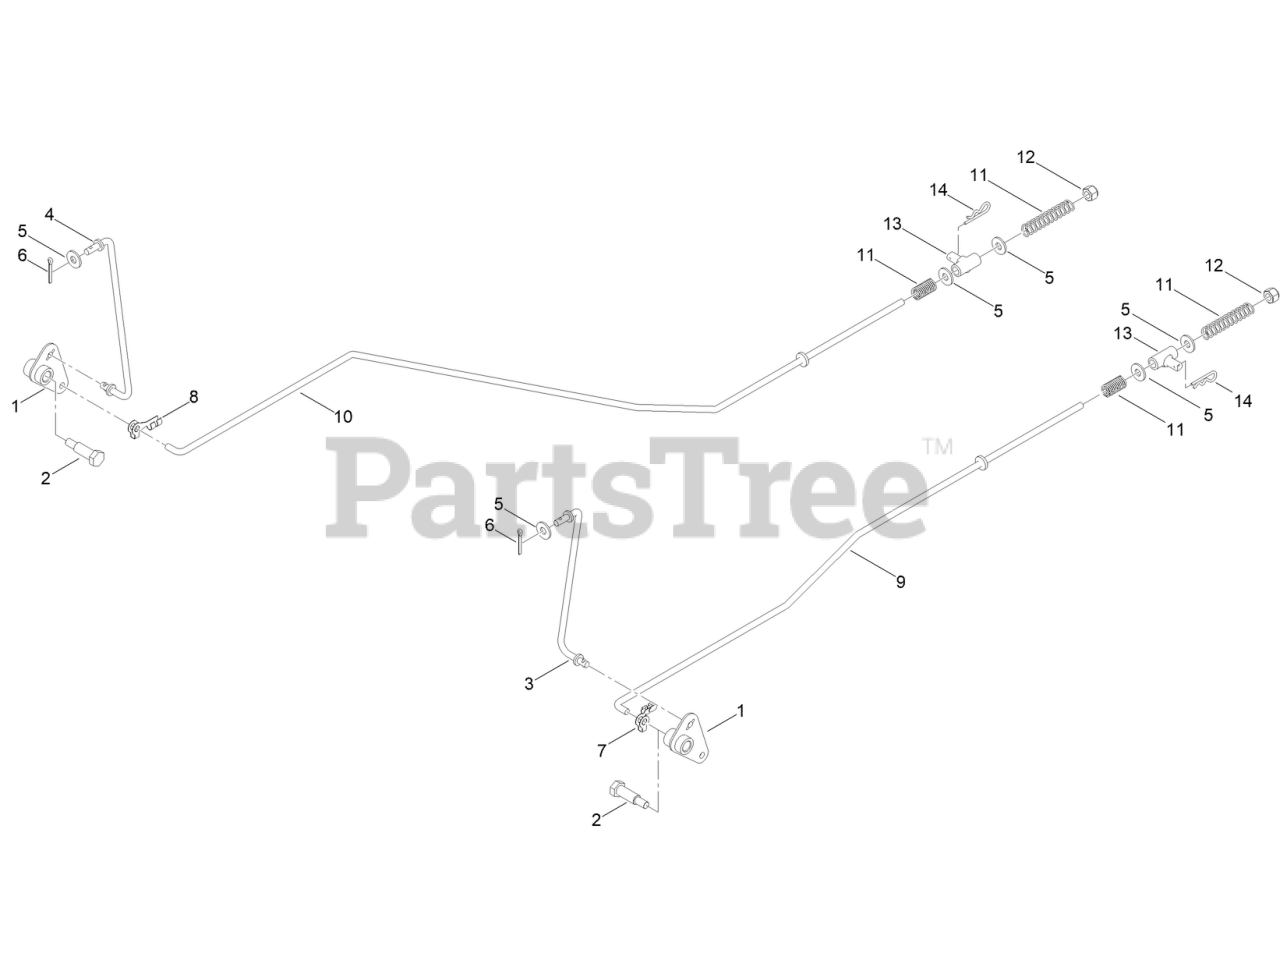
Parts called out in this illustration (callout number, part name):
1	BELLCRANK
2	BOLT-SHOULDER
3	LINK-BRAKE, LH
4	LINK-BRAKE, RH
5	WASHER
6	PIN-COTTER
7	CLIP-ROD, LH (7L, 1/4IN)
8	CLIP-ROD, RH (7R, 1/4IN)
9	ROD-BRAKE LH
10	ROD-BRAKE, RH
11	SPRING-COMPRESSION
12	NUT-LOCK, NI
13	MOUNT-PIVOT
